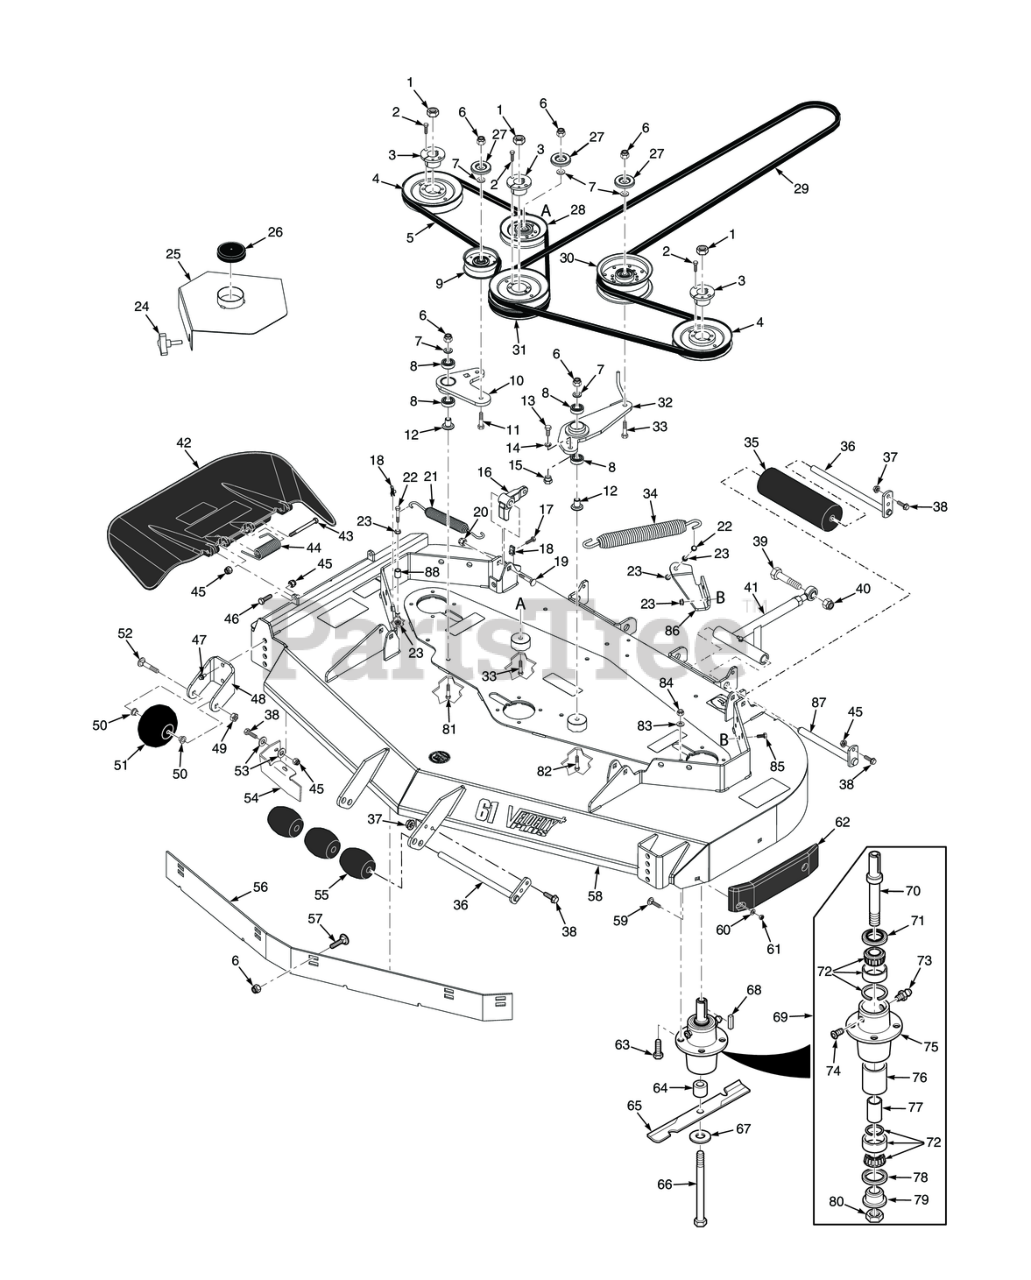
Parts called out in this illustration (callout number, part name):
1	Hex Locknut, Elastic Stop, 3/8-16
2	Bolt, Hex Head 1/4-20 x 1" Grade 8 Black
3	Hub, Tapered 1-1/8" Bore
4	Pulley, Tapered Bore 6.33" Dia.
5	Belt, Deck Drive R.H.
6	HEX NUT, ELASTIC STOP LOCK, 3/8-16
7	Flatwasher, 3/8 (.391 x .938 x .105 HD) Grade 8
8	BEARINGS, BALL, NEUTRAL RETURN
9	Pulley, 3-1/2" Dia.
10	Idler Arm
11	Capscrew, Hex Head 3/8-16 x 2-1/2"
12	Pivot, Idler Short
13	Bolt, Hex Head 7/16-14 x 1"
14	Lockwasher, 7/16� Spring
15	Boss, Spring Anchor - LH
16	Lever, Deck Level
17	Bolt, Hex Head 3/8-16 x 2" Special Lock
18	U-Nut, 3/8-16 (short)
19	Bolt, Carriage 7/16-14 x 2-1/4"
20	HEX LOCKNUT, ELASTIC STOP, 7/16-14
21	Spring, RH Deck Drive
22	Bolt, Hex Head 3/8-16 x 1-1/2" Grade 8 Black
23	NUT, 3/8-16 SERRATED FLANGE HEX HEAD
24	Knob, w/stud 3/8-16 x 1-1/4"
25	Belt Cover Weldment
27	Quick Pin, 5/16" Dia.
28	IDLER PULLEY, "V" GROOVE
29	BELT, DECK DRIVE - SMTC-61V
30	Pulley, Idler 5" Dia.
31	Pulley, Double Groove 6.33" Dia.
32	Idler Arm
33	Bolt, Hex Head 3/8-16 x 3" - 52"
34	Spring, L.H. Deck Drive
35	Wheel, Anti-ScalpRelief Fitting, Tapered Spindle
36	Shaft Weldment, Guide Roller
37	Nut, Flange Head Elastic Stop 5/16-18
38	Bolt, Heax Head 5/16-18 x 1" (48V / 52V)
39	BOLT, HEX HEAD 5/8-11 X 4-1/2"
40	HEX LOCKNUT, ELASTIC STOP, 5/8-11
41	Push Arm (Includes 64,60,62)
42	Discharge Chute Advantage - Large
43	Bolt, 5/16-18 x 4-3/4" Hex Head
44	Spring, Discharge Chute
45	HEX NUT, ELASTIC STOP LOCK, 5/16-18
46	Bolt, Hex Head 5/16-18 x 1-1/2" - Front
47	Capscrew, 3/8-16 x 1.0" Serrated Flange Hex Hd
48	Bracket, Anti-Scalp Wheel
49	Bolt, Hex Head 3/8-16 x 1" Ser. Flg.
50	Bushing, .376" I.D. Oilite
51	Bolt, Carriage 3/8-16 x 4"
52	Bolt, Hex Head 3/8-16 x 3-1/2"
53	Flatwasher, 5/16-.375 x .875 x .083 (35BV & 37BV-EFI)
54	Turbo Baffle, Bolt On
55	Wheel, Anti-Scalp
56	Baffle Custom-Cut, 61V (7-Position)
57	Carriage Bolt, 3/8-16 x 1.0"
58	Cutter Deck Velocity Plus
59	Bolt, 5/16-18 x .75 RHSN Carriage
60	Flatwasher, 5/16-.344 x .688 x .065 (48V / 52V)
61	Nut, Center Lock, 5/16-18(32)
62	Pad, Deck Wear
63	Bolt, Hex Head 5/16-18 x 1-3/4" Grade 8
64	Spacer, Spindle Bottom
65	Cutter Blade, 21" Standard
66	BOLT, HEX HEAD, 5/8-11 X 9-1/2 GR.5
67	Flatwasher, 5/8-.688 x 1-3/4 x .134 HD
68	Key, 1/4 x 1/4 x 2.0"
69	Cutter Spindle Assembly
70	Spindle Shaft, Tapered Brng
71	SEAL, 2.00 O.D. X 1.50 BORE
72	Tapered Bearing Set (Two Bearings W/Race)
73	GREASE FITTING, STR. 1/4-28 SELF TAP.
74	RELIEF FITTING, TAPERED BEARING SPINDLE
75	Housing, Spindle
76	Spacer, Outside, Cutter Spindle
77	SLEEVE, CUTTER SPINDLE
78	Seal, 2.00" O.D. x 1.625" Bore
79	SPINDLE BUSHING, BOTTOM
80	Nut , Spec ial 1 -1/ 1 6 - 1 8
81	Bolt, Hex Head 3/8-16 x 2-1/4" - 61"
82	Capscrew, Hex Head 3/8-16 x 3.25"
83	Lockwasher, 5/16 (.317 x .586 x .078) Helical Spring
84	Lock Nut, 5/16-18 Elastic Stop Grade 8
85	Bolt, Hex Head, 3/8-16 x 1 Gr. 5
86	Bracket, Spring Anchor
87	Shaft Weldment, Pusharm
88	SPACER, IDLER
